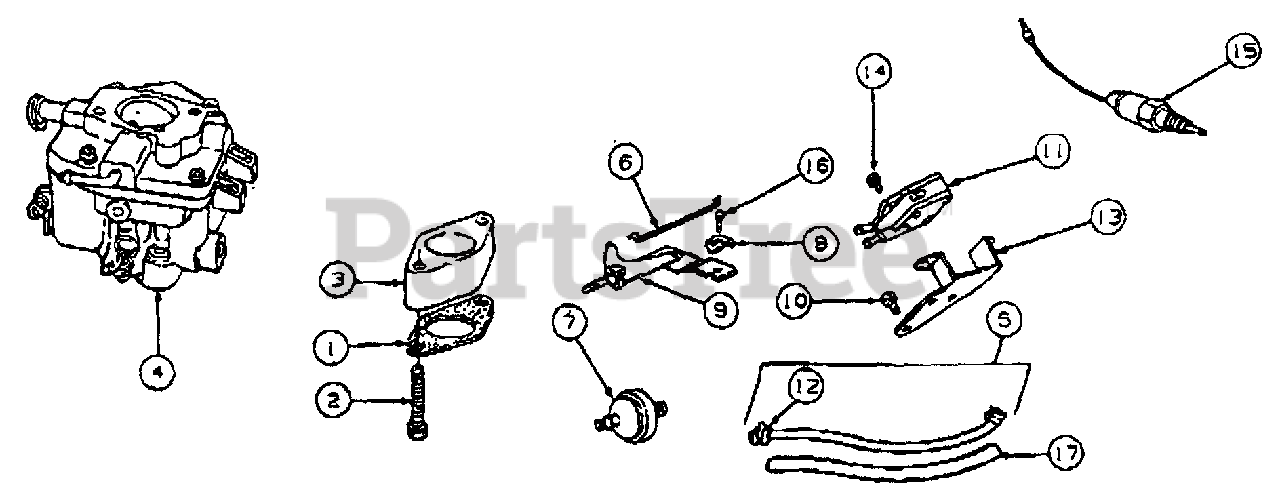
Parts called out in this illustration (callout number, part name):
1	Gasket, Carburetor Mtg
2	Screw, Sems
3	Spacer, Carburetor
4	Carburetor Assy
5	Line, Fuel
6	Link, Choke
7	Filter, Fuel
8	Clamp, Casing
9	Bracket, Choke
10	Screw, Sems
11	Pump, Fuel
12	Clamp, Fuel Line
13	Bracket. Fuel Pump
14	Screw, Mtg
15	Solenoid
16	Screw, Hex Hd
17	Insulation, Fuel Line
